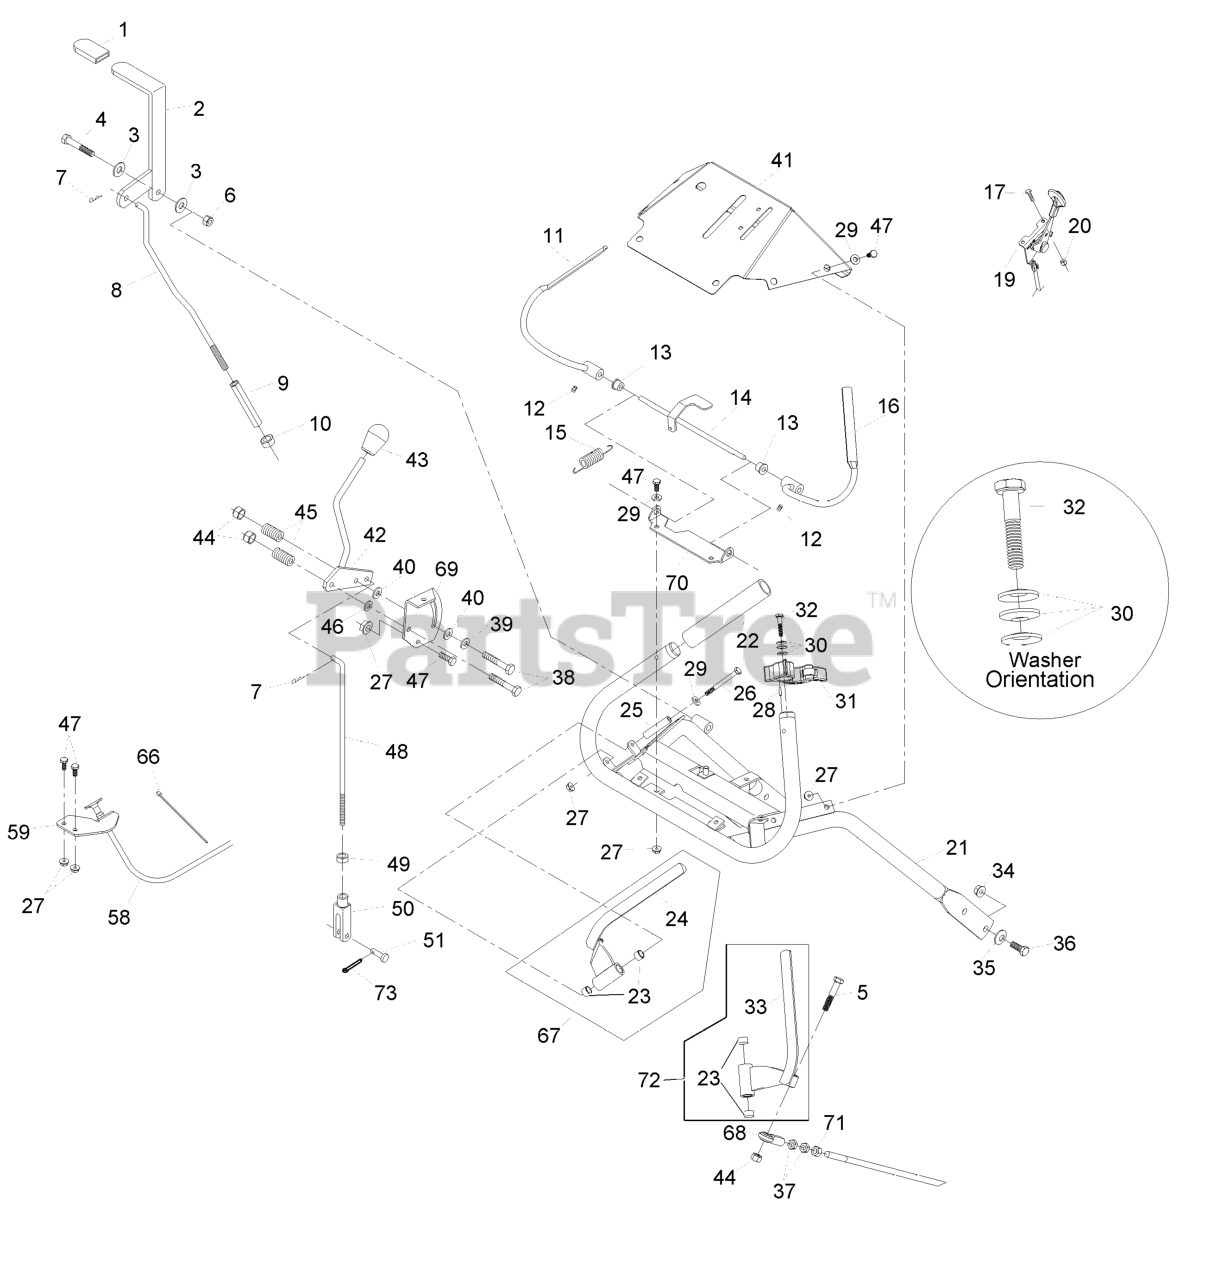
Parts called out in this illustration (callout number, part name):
1	GRIP-LEVER
3	WASHER-FLAT
4	SCREW-HH
5	SCREW-HH
6	NUT-LOCK, NI
7	PIN-COTTER
8	LINK,BLADE ENGAGE (PLTD)
9	TURNBUCKLE
10	NUT-HEX
11	WLD,LH OPC LEVER
12	SCREW-SET
13	BUSHING-NYLON
14	WLD,OPC LEVER AXLE
15	SPRING-EXTENSION
16	WLD,RH OPC LEVER
17	BOLT-CARR
19	CONTROL, THROTTLE
20	NUT-LOCK, NI
21	WLD,UPPER ECS HANDLE
22	GRIP-BAR, HANDLE
23	BUSHING-SLEEVE
24	WLD,LH DRIVE LEVER
25	BUSHING-LEVER, DRIVE
26	SCREW-HH
29	WASHER-FLAT
30	WASHER-SPRING
31	ASM,LATCH RH THUMB
31	ASM,LATCH LH THUMB
32	SCREW-HH
33	WLD,RH DRIVE LEVER
34	NUT-HHF, WHIZ
35	WASHER-BELLEVILLE
36	SCREW-HH
37	NUT-HJ
38	SCREW-HH
39	WASHER-FRICTION
40	WASHER-FRICTION
41	ASM,CONSOLE W/DECALS
43	KNOB, FE.LCKG. BLACK
44	NUT-LOCK, NI
45	SPRING-COMPRESSION
46	WASHER-PLAIN
47	SCREW-HH
48	ROD,SPEED CONTROL
49	NUT-JAM
50	YOKE-ADJUSTABLE
51	PIN-CLEVIS
58	CABLE-CHOKE
59	BRACKET-CABLE, CHOKE
66	TIE-CABLE
67	DRIVE LEVER-ASM, RH
68	JOINT-BALL, END
69	BRACKET,SHIFTER SLIDE (PL
70	BRACKET,OPC AXLE
71	NUT-HEX
72	DRIVE LEVER-ASM, LH
73	PIN-COTTER
